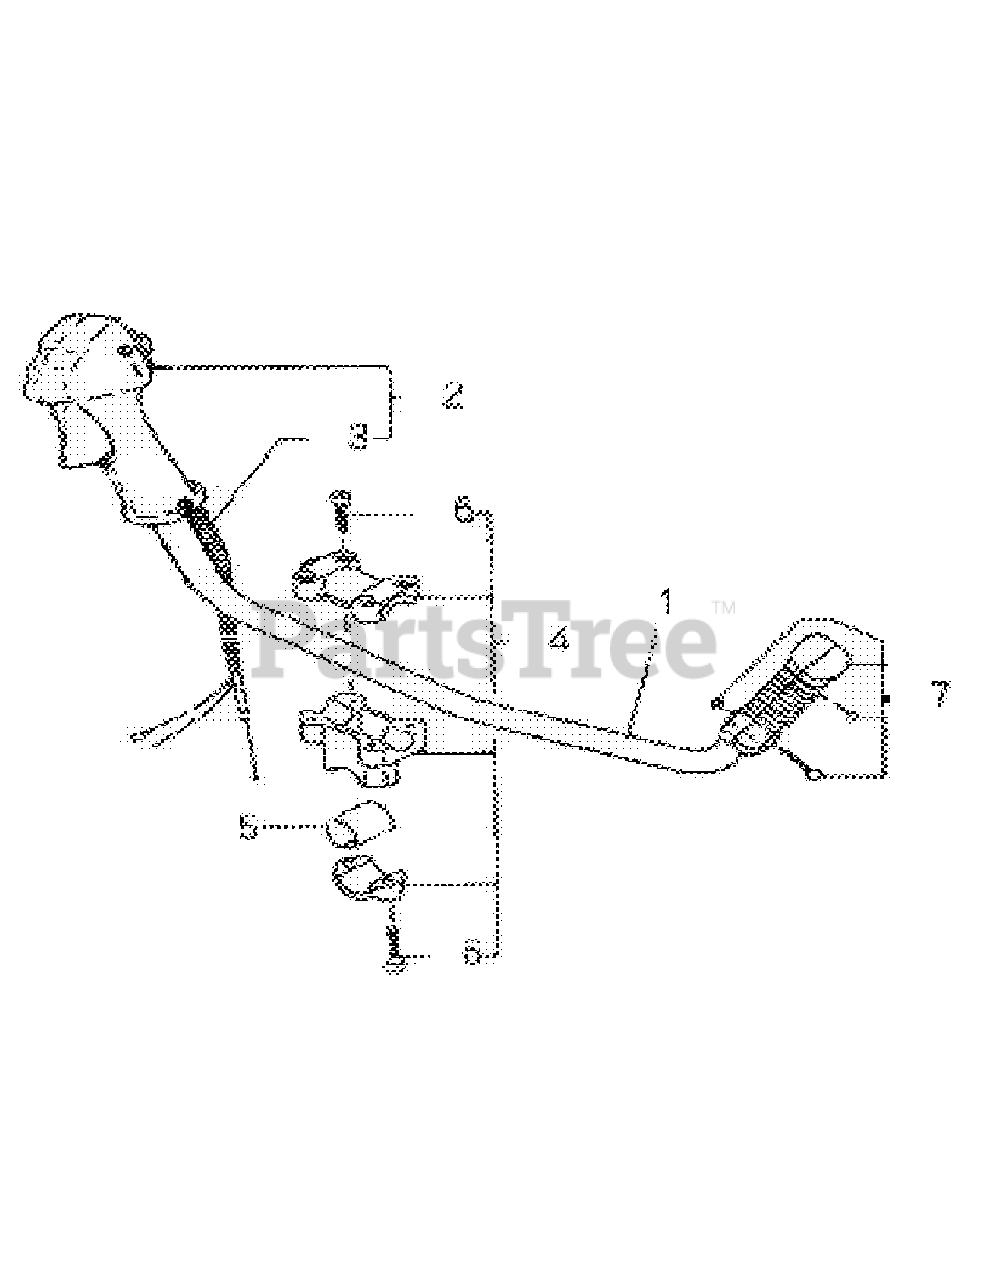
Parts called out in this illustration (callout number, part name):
2	Throttle Lever Assembly
3	Wire, Throttle
4	Holder, Handle
6	Bolt, M6X26
7	Grip Assembly
